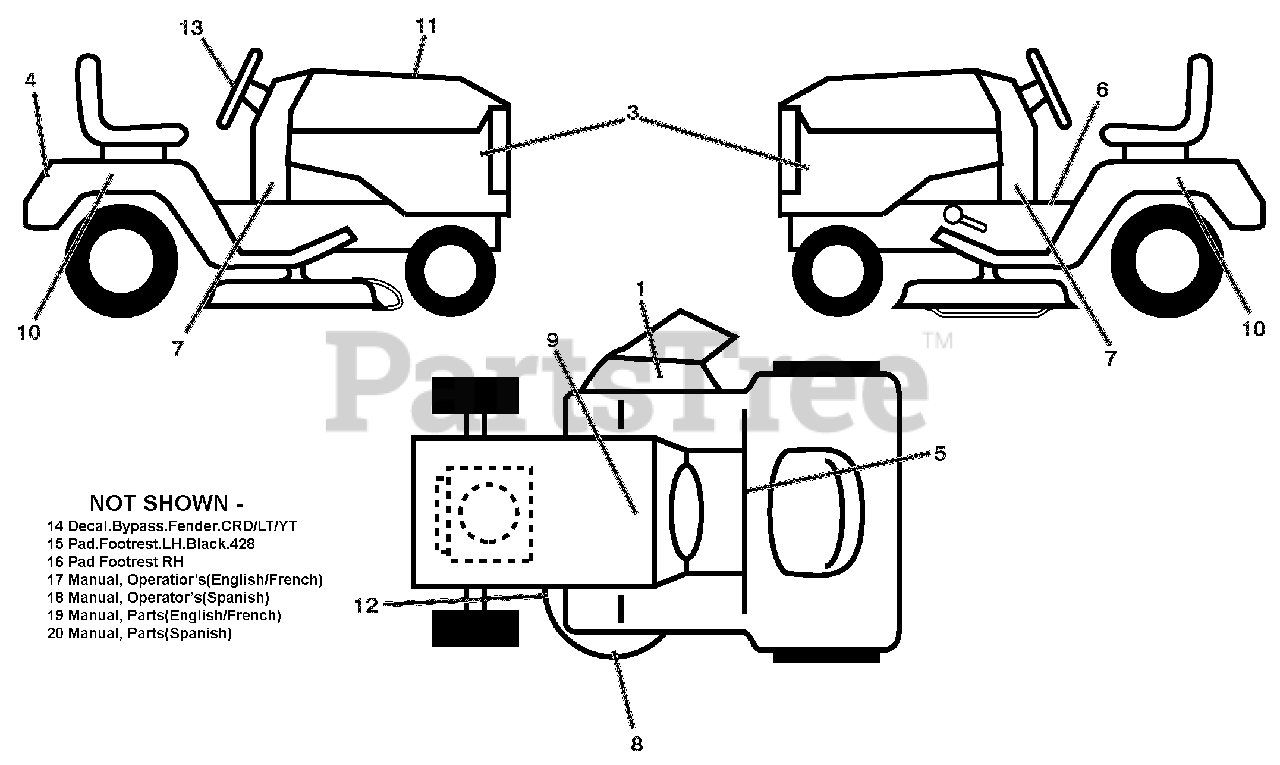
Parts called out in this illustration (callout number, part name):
1	DECAL DECK/DEFLECT. WARNING
3	DECAL.SDPNL.PWRDBY KOHL.ARIENS
4	DECAL.FENDER.REAR.ARIENS
5	DECAL.FENDER
6	DECAL.WARNING.START
7	DECAL.LOWER.DASH
8	DECAL.MOWER.CAUTION
9	DECAL.BAT.DAN/POI P/L SYM.WPN
10	DECAL.FENDER.SIDE.HYDRO.ARIENS
11	DECAL REPLACEMENT
12	DECAL.MOWER.SCH
13	DECAL.WHEEL.STEER.ARIENS
